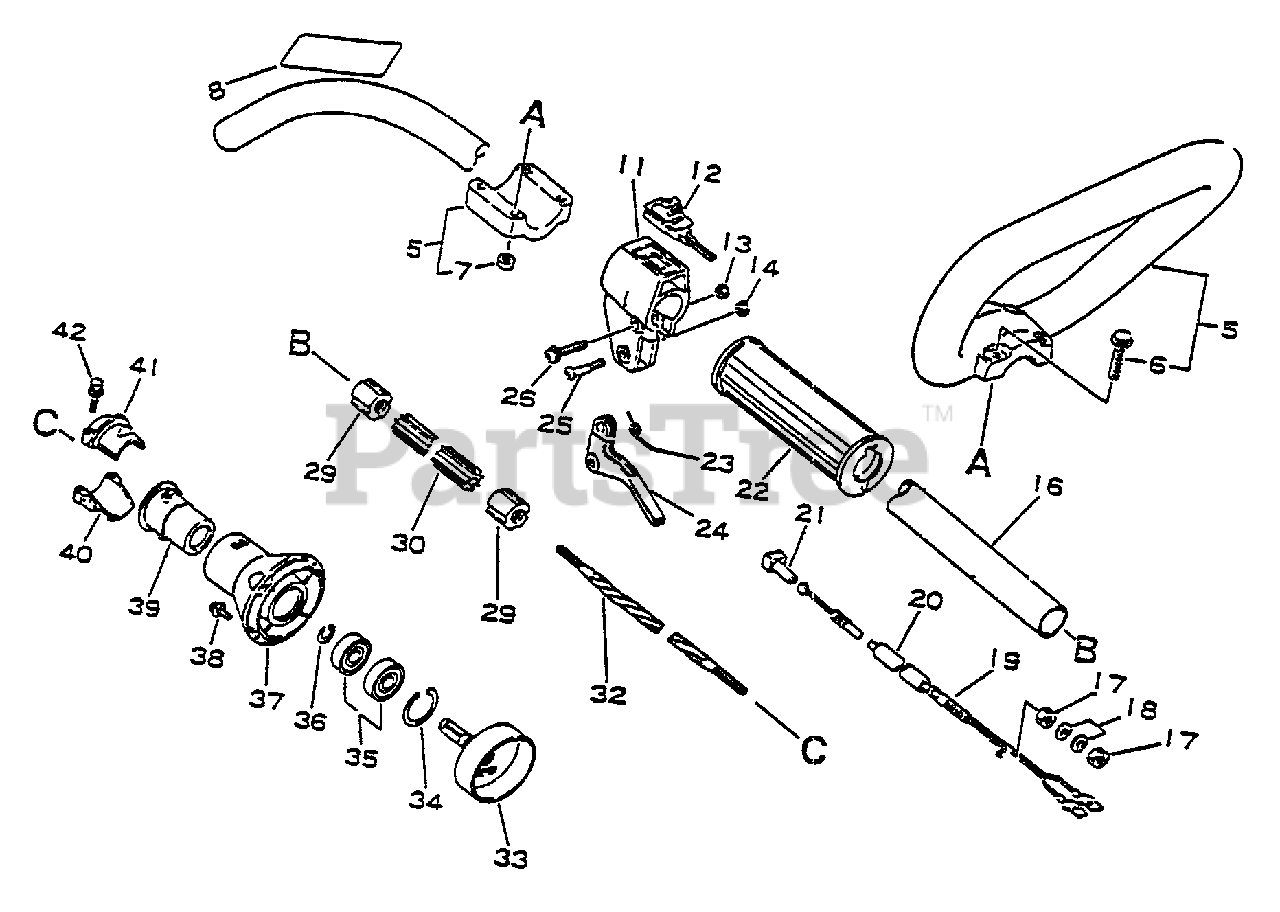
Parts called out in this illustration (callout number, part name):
5	LOOP HANDLE ASSY
7	SCREW - 5X35
8	LABEL - CAUTION
11	BRACKET, THROTTLE CONTROL
12	IGNITION SWITCH ASSY
14	LOCKNUT - 5
16	MAIN PIPE ASSY
18	WASHER - 6
19	CABLE, THROTTLE
20	TUBE - VINYL
21	GUIDE, CABLE
22	GRIP, HANDLE
23	SPRING, TRIGGER
24	TRIGGER, THROTTLE
25	SCREW - 5X30
26	SCREW - 5X30
30	LINER - FLEXIBLE
32	DRIVESHAFT - FLEXIBLE
33	DRUM, CLUTCH
34	RING, RETAINING - 28
35	BEARING, BALL - 6001
36	RING, RETAINING - 12
37	CASE, CLUTCH - GRAY
38	SCREW - 5X16
40	CLAMP, MAIN PIPE - UPPER
41	CLAMP, MAIN PIPE
42	BOLT - 5X25
44	SPANNER
45	SPANNER - 8X10mm
46	T-WRENCH - 17X19mm
